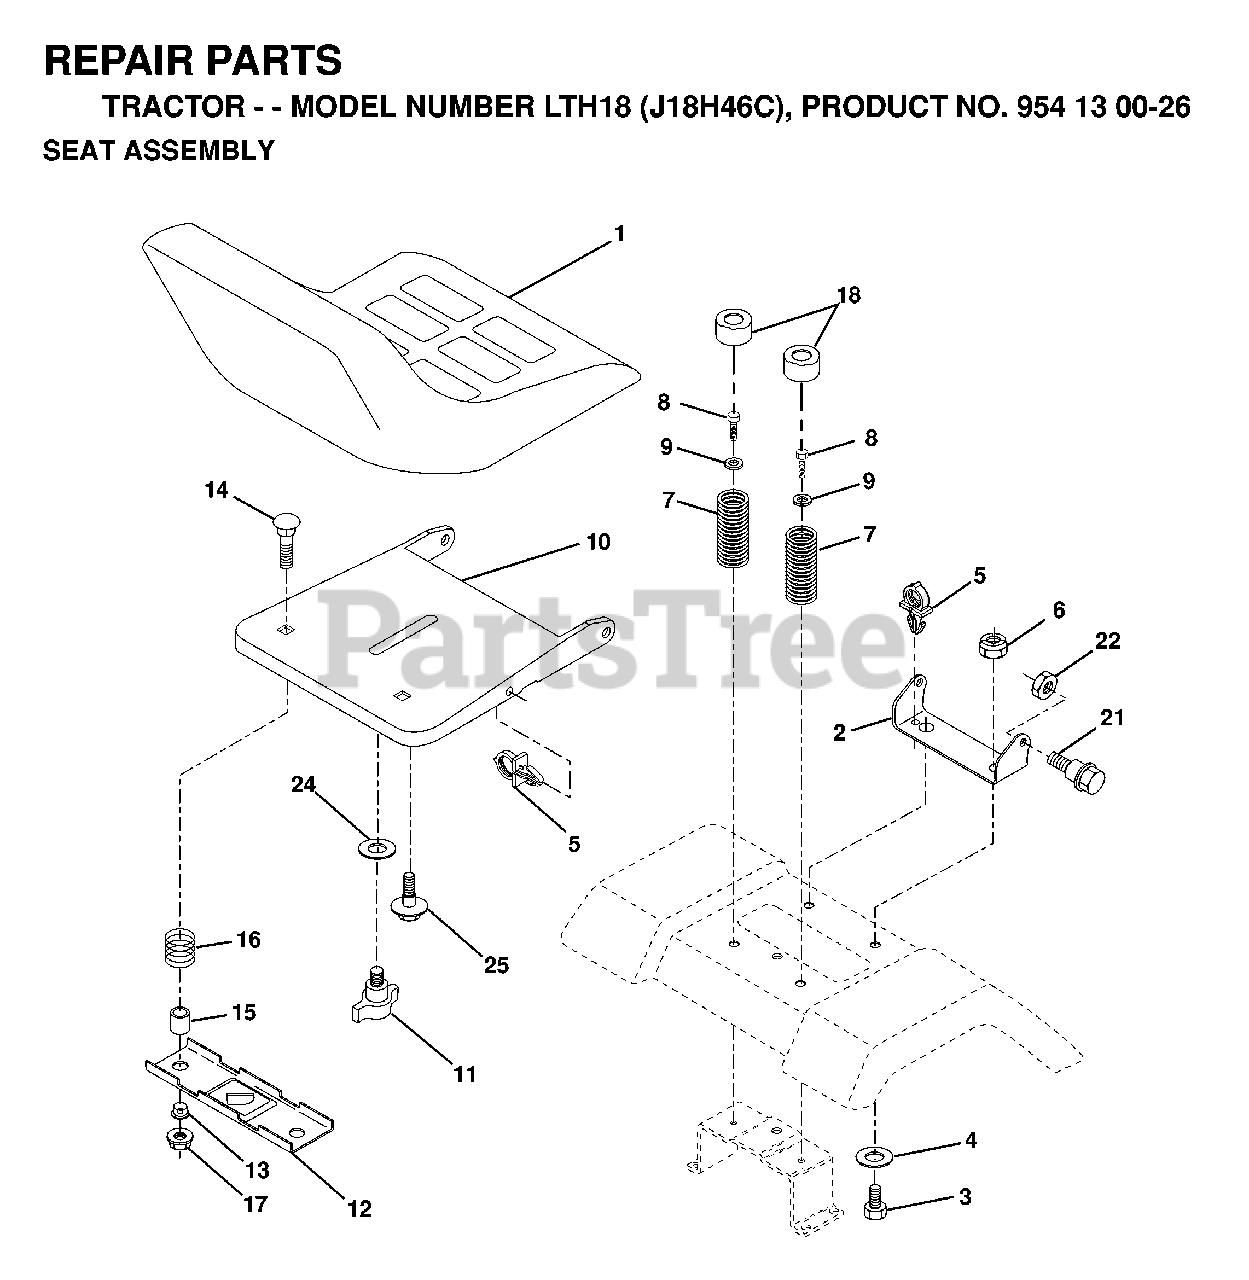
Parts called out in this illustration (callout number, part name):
2	SEAT PIVOT BRKT
3	BOLT
4	WASHER PM
5	PUSH CLIP
6	NUT
7	SPRING COMPRESSION
8	SCREW GTV
9	WASHER
10	PAN, SEAT
11	KNOB 1/2" YT
12	BRKT SWITCH
14	BOLT.ROUND.HEAD.SQUARE.NECK
15	SPACER SPLIT
16	SPRING COMPRESSED
17	NUT T
18	CAP SPRING
21	BOLT SHOULDER 5/16-18
22	LOCKNUT
25	BOLT,SHOULD
